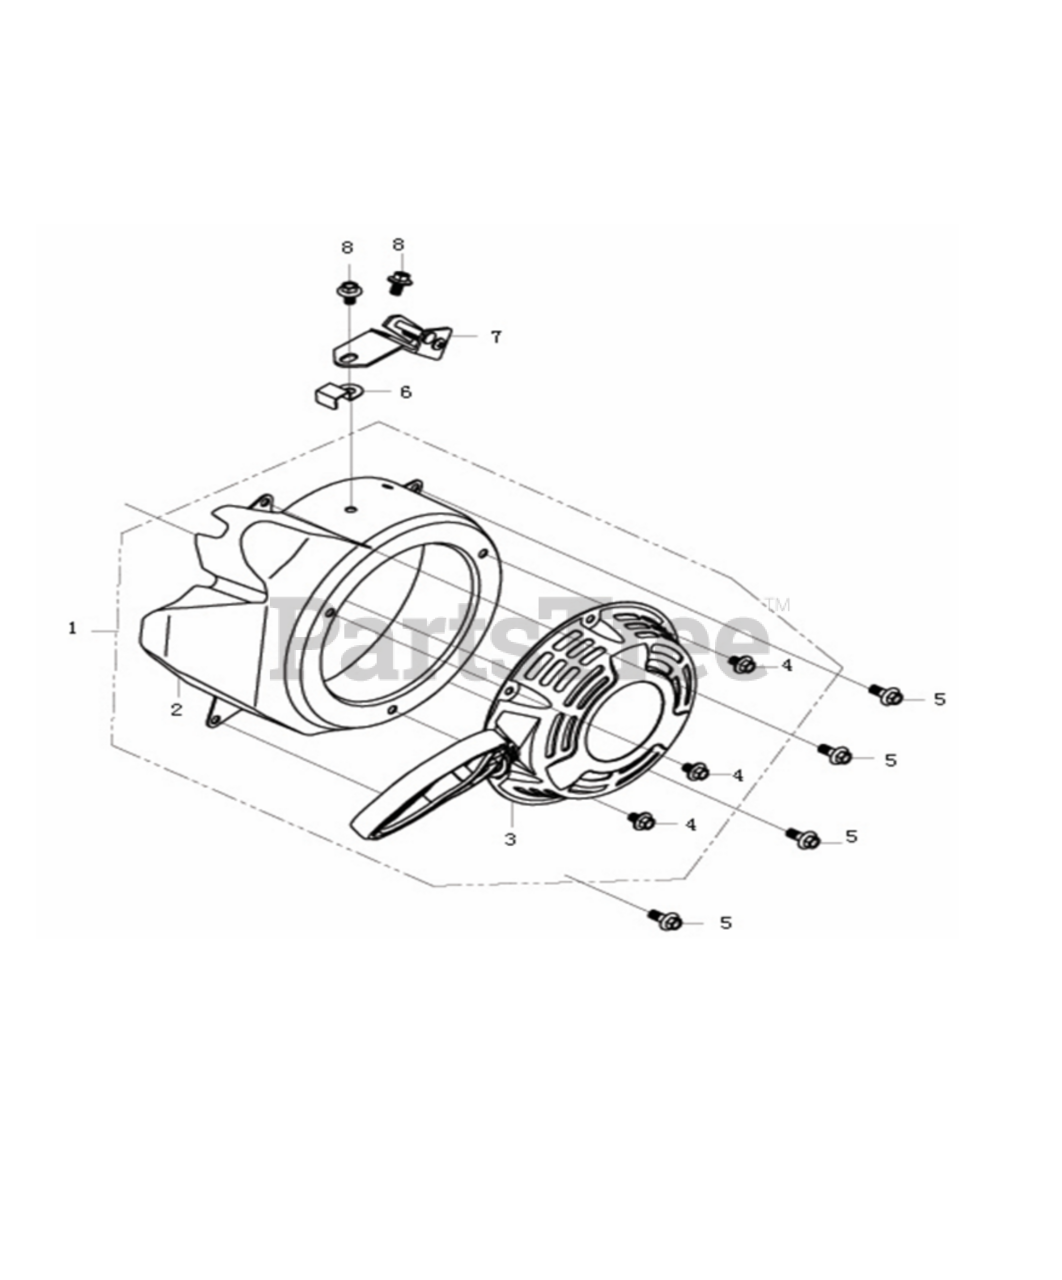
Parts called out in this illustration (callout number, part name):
1	Manual starting assembly
2	Fan cover comp.
3	Recoil Assembly
4	Hexagon bolt with flange
5	Hexagon bolt with flange
6	Cable cleat
7	Throttle handle combination
8	Hexagon bolt with flange
